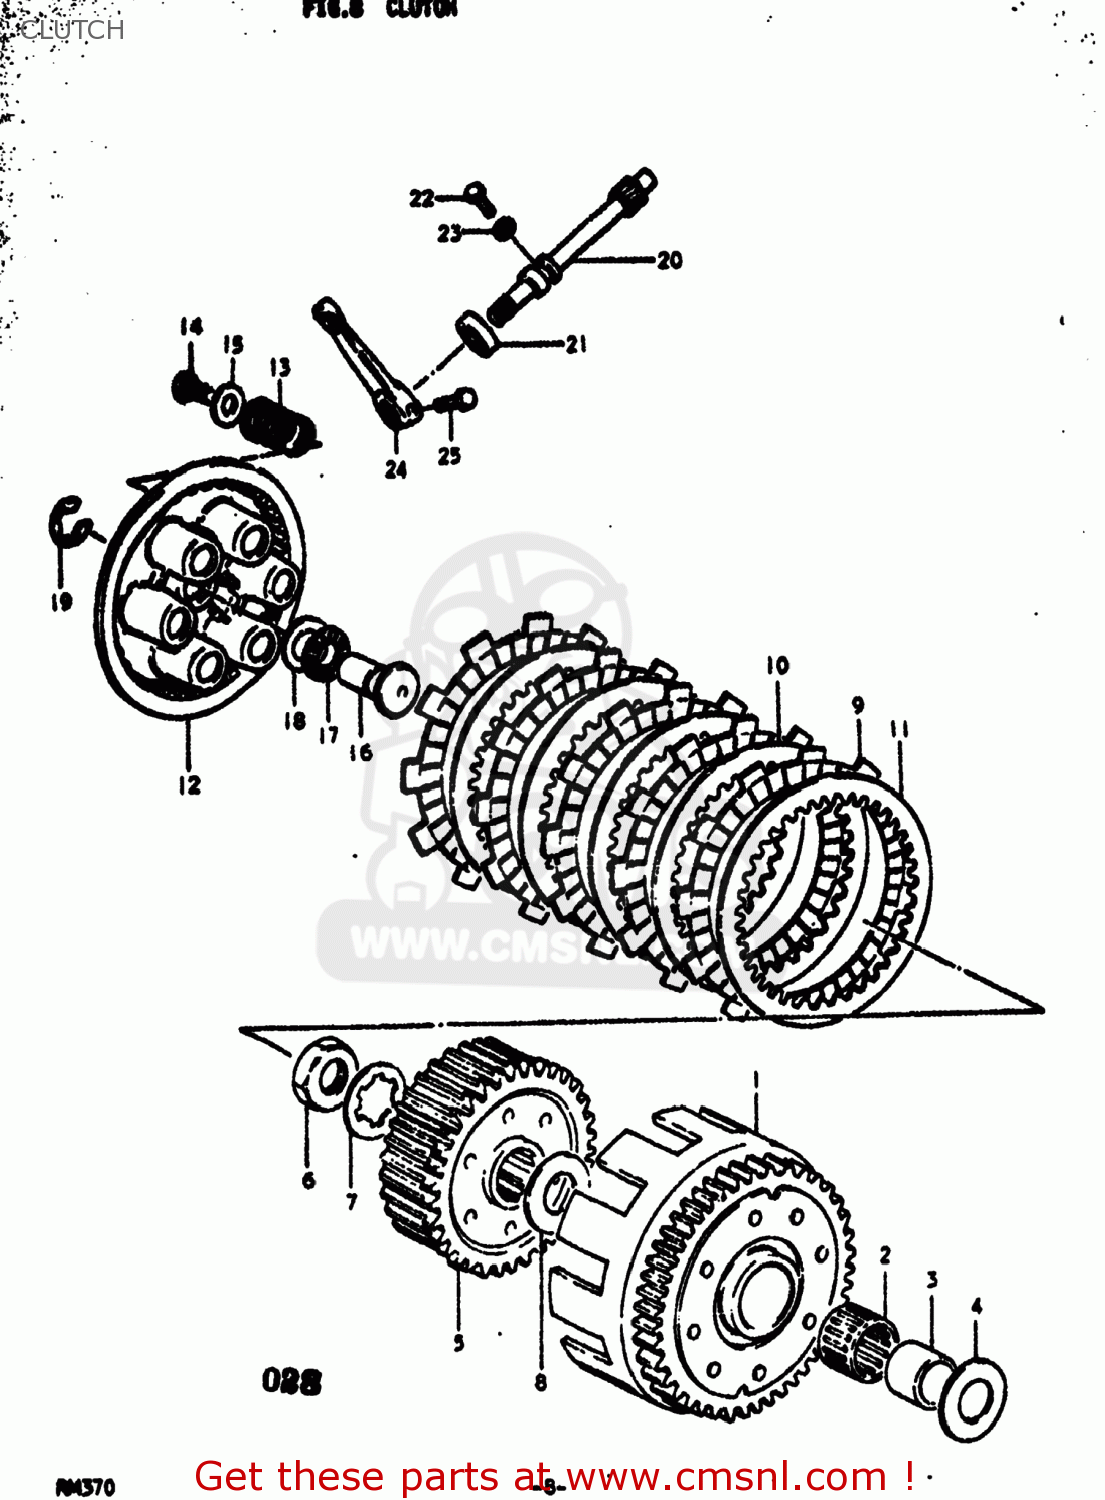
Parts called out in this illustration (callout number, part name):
1	GEAR ASSEMBLY,PRIMARY DRIVE
2	BEARING(30X35X19.8)
3	SPACER
4	WASHER
5	HUB,CLUTCH SLEEVE
6	NUT
7	WASHER,LOCK
8	WASHER
9	PLATE,CLUTCH DRIVE (MCA)
10	PLATE,CLUTCH DRIVEN (NAS)
11	PLATE,CLUTCH DRIVEN(T:2.0) (NAS)
12	DISC,CLUTCH PRESSURE
13	SPRING
14	BOLT
15	WASHER
16	RACK,CLUTCH RELEASE
17	BEARING(15X28X2)
18	WASHER
19	E RING 12MM
20	PINION,CLUTCH RELEASE
21	OIL SEAL
22	BOLT(6X12)
23	WASHER
24	ARM,CLUTCH RELEASE
25	BOLT
